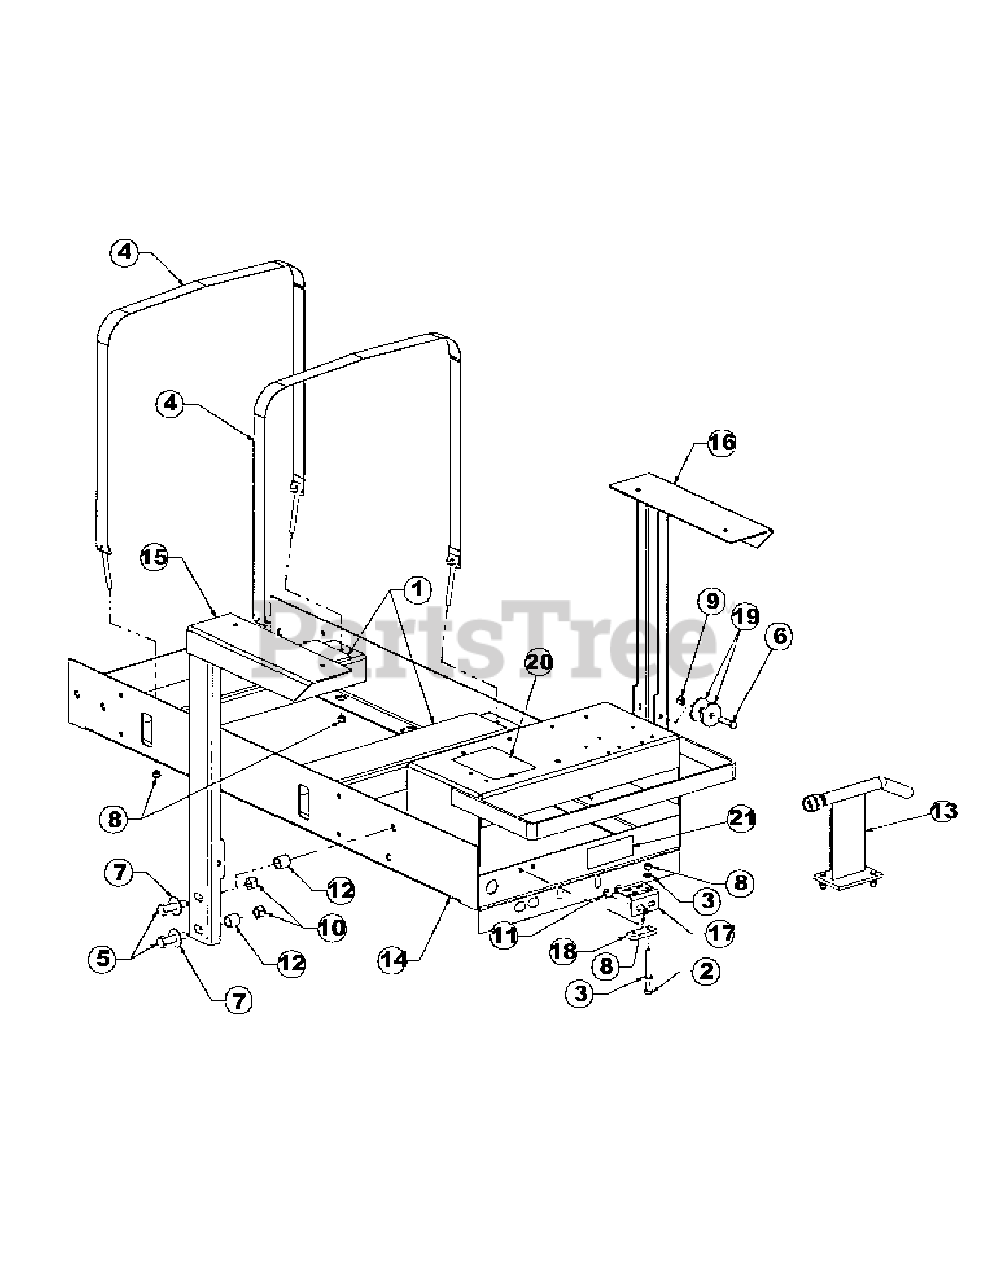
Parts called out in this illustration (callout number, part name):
1	Adhesive Back Foam, 1/4,4
2	Hex Cap Screw, 5/16-18, 3-1/4
3	Flat Washer
4	50 Gal Strap Tank, w/3'' T-Bolt
5	Hex Cap Screw, 1/2-13 x 2.00
6	Hex Cap Screw, 3/8-16 x 1.25
7	Flat Washer, 1/2
8	Nylock Nut, 5/16-18
9	Nylock Nut, 3/8-16
10	Nut, 1/2-13, Nylon Insert
11	Carriage Bolt, 5/16-18 x 3/4
12	Spacer, .635ID x .86
13	Air Gap Filler Kit
14	Main Frame Assembly
15	Reel Support Assembly - LH
16	Reel Support Assembly - RH
17	Drain Mounting Bracket
18	Strainer Block Spacer
19	Washer, .4375ID x 1.75OD x .25
20	Decal, Saftey Procedures
21	Decal, CCC, Small
